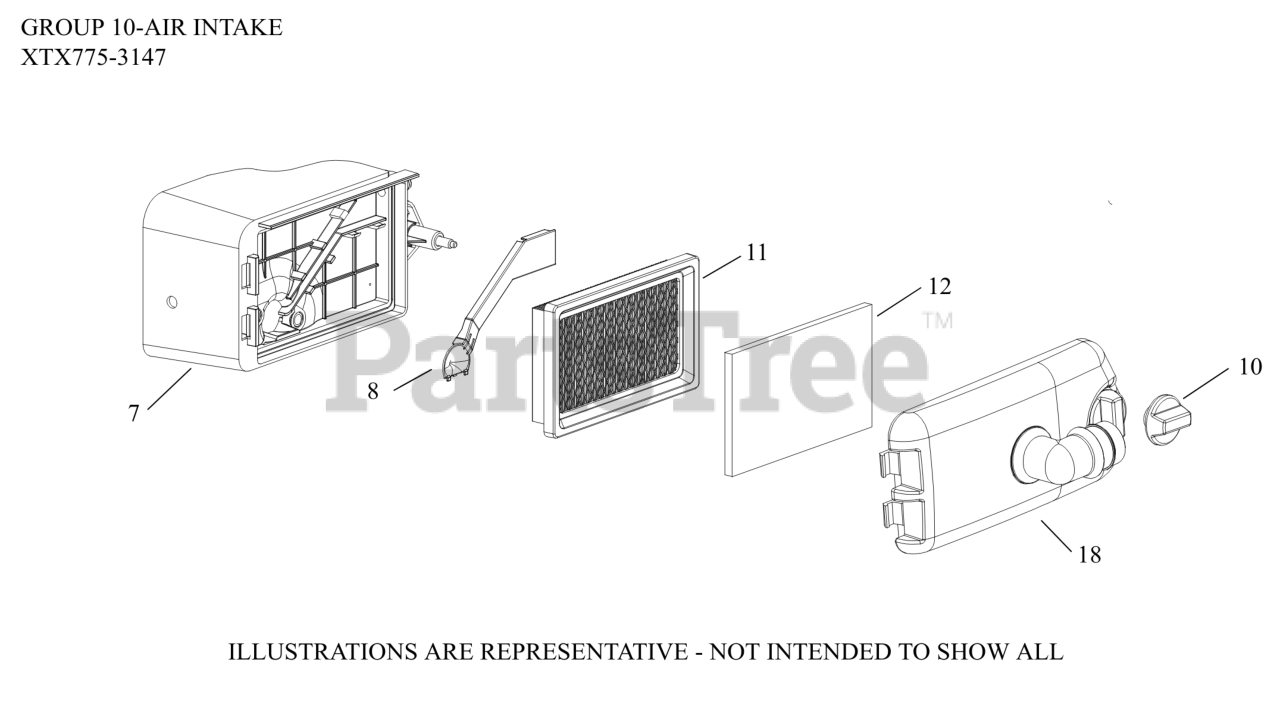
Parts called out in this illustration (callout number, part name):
7	KIT, AIR CLEANER BASE
8	COVER, A/C BASE (BREATHER GAS)
10	KNOB-USE 14 341 07-S
11	ELEMENT, AIR FILTER
12	ELEMENT, PRE-CLEANER
18	COVER ASSEMBLY, AIR CLEANER (SERVICE)
